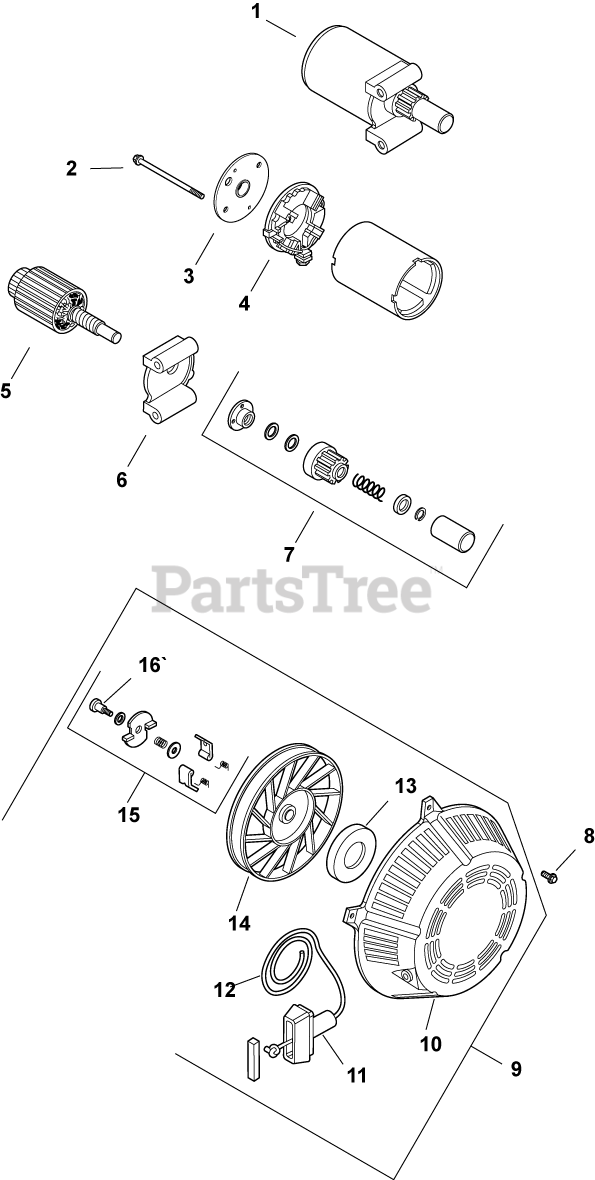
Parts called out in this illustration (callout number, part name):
1	ELECTRIC STARTER-BENDIX DRIVE
2	BOLT, THRU #10-24X4 13/32" - DISCONTINUED
3	CAP - (#DSC)
4	BRUSH KIT
5	ARMATURE - DISCONTINUED
6	CAP, DRIVE END - (#DSC)
7	KIT, DRIVE
8	SCREW, HVY FLG M5X.8X10
9	STARTER ASSY,RETRACTABLE-USE 12 165 03-S
10	HOUSING - DISCONTINUED
11	HANDLE, RECOIL STARTER
12	ROPE - DISCONTINUED
13	SPRING & KEEPER - (#DSC)
14	PULLEY - (#DSC)
15	KIT, DOG REPAIR - (#DSC)
16	SCREW - DISCONTINUED
